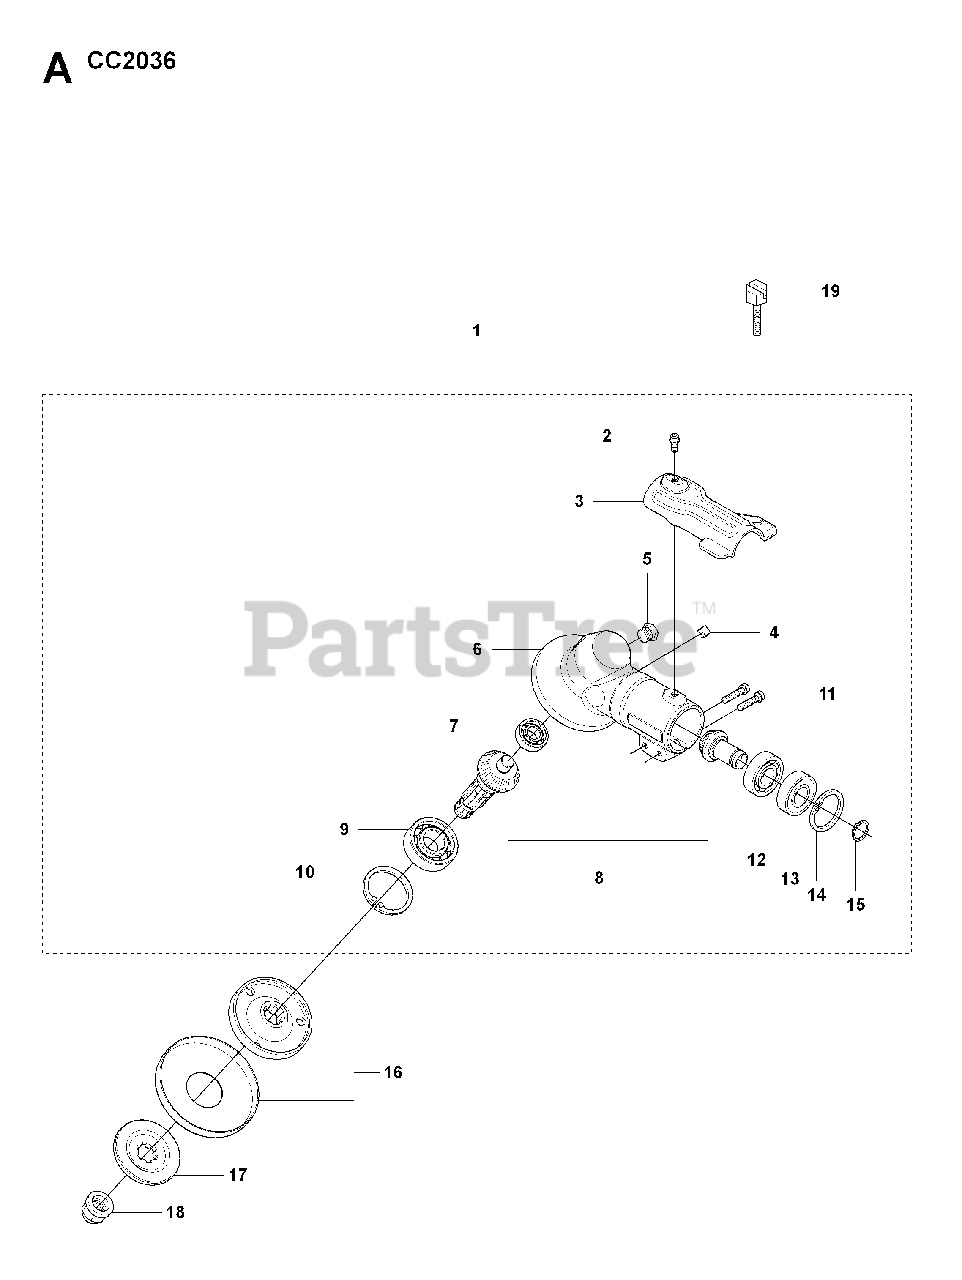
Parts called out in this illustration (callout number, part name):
1	GEAR COMPLETE
2	SCREW
3	RP HOLDER
5	PLUG
7	BALL BEARING 24X9X1/609ZR
8	SPARE PARTS KIT
9	BALL BEARING
10	RETAINING RING
12	BALL BEARING
13	BALL BEARING
14	RETAINING RING SGH 28
15	SEEGER CLIP
16	RP CARRIER
17	RP FLANGE
18	BLADE NUT
